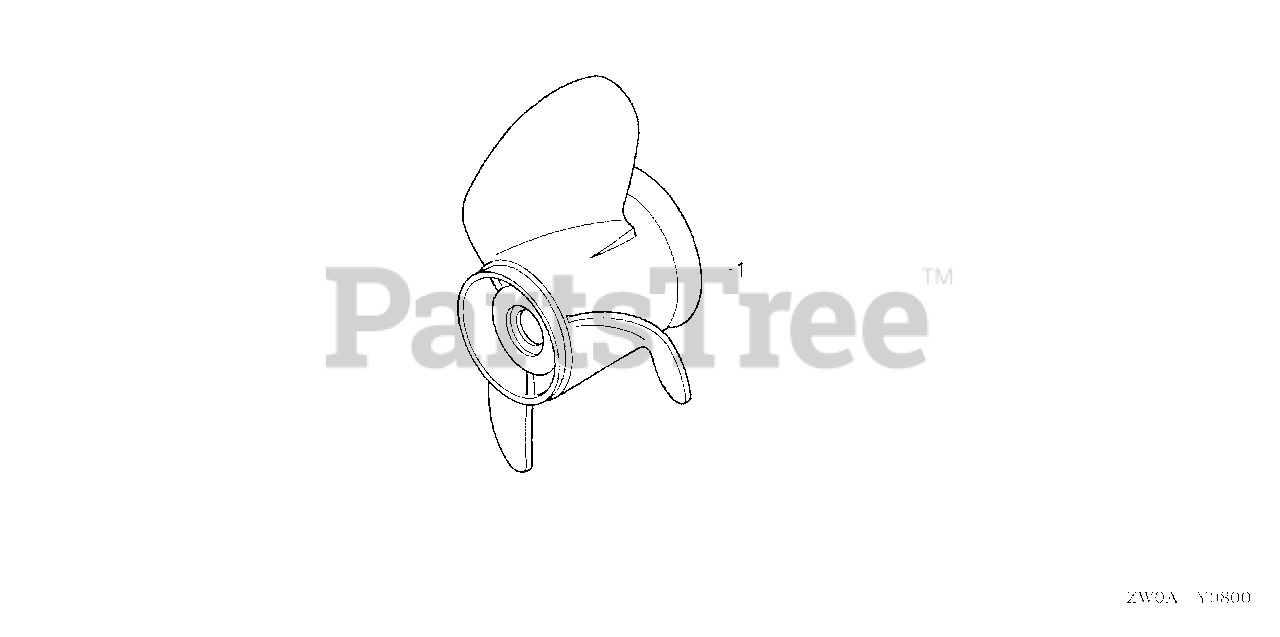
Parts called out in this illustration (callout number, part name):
1	PROPELLER, THREE-BLADE (14X11)
1	PROPELLER, THREE-BLADE
1	PROPELLER, THREE-BLADE (13X19)
1	PROPELLER, THREE-BLADE (13X21)
